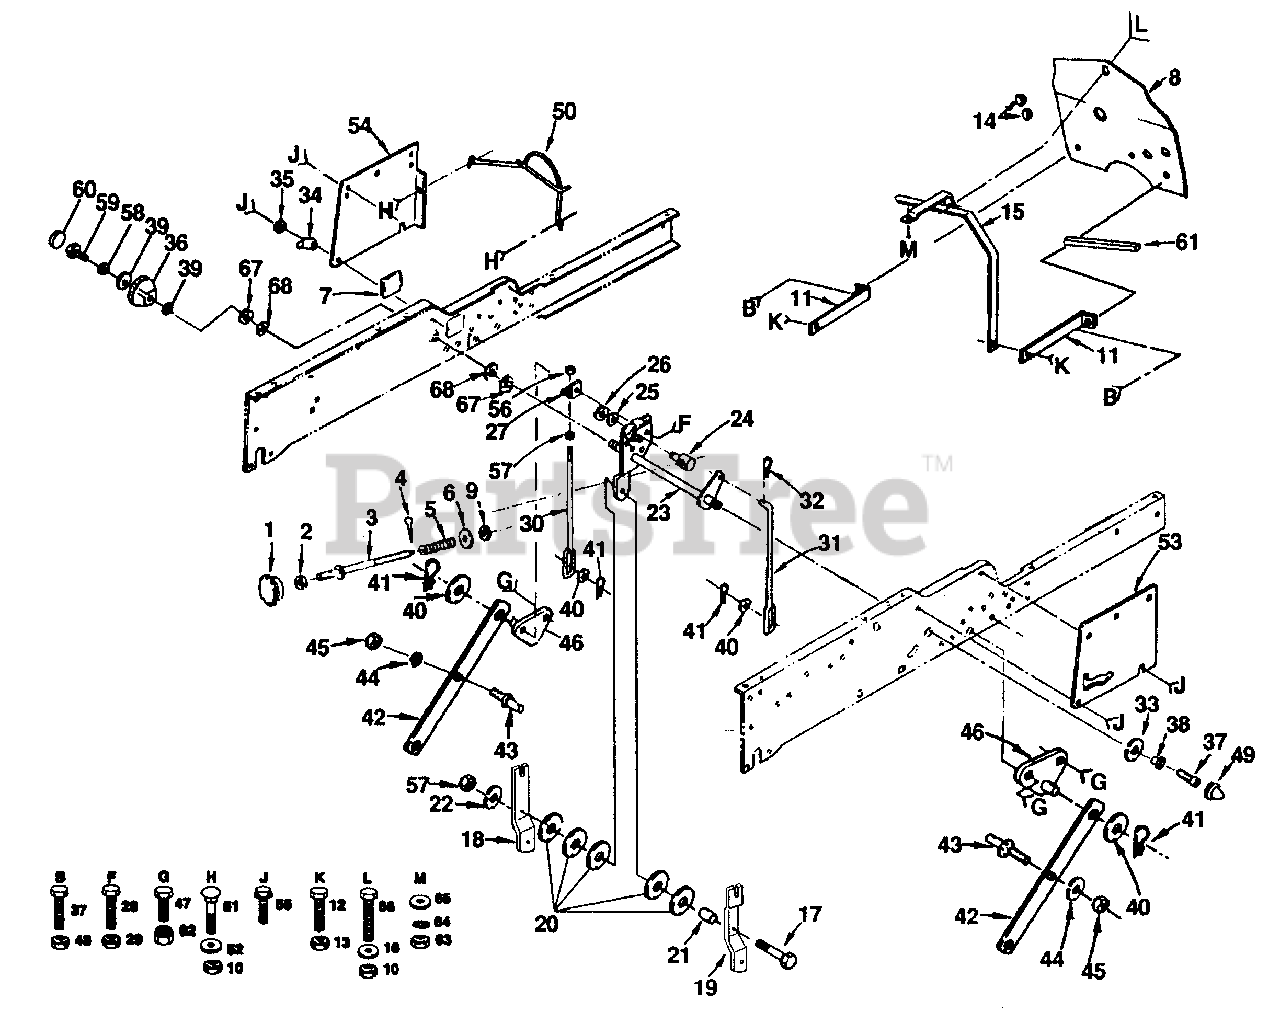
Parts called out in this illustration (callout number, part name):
1	Handle, Adjust, Lift
2	Nut, Hex, Jam 3/8-16
3	Rod, Adjust, Lift
4	Pin, Cotter 3/32 x 3/4
5	Spring
6	Washer 13/32 x 5/8 x 16 Gauge
7	Cover, Access
8	Shield, Head, Read
9	Nut, Special
10	Locknut 5/16-18
11	Brace, Head Shield
12	Bolt, Hex 1/4-20 x 1/2
13	Locknut 1/4-20
14	Grommet
15	Support Assembly, Dash
16	Washer 11/32 x 3/4 x 16 Gauge
17	Bolt 3/8-16 x 1-3/4
18	Bracket, Lift, L.H.
19	Bracket, Lift, R.H.
20	Washer 17/32 x 1-1/2 x 10 Gauge
22	Washer, Lock 3/8
23	Shaft, Lift
24	Trunnion, Stop Depth
25	Washer 15/32 x 3/4 x 16 Gauge
27	Bracket, Lift L.H.
28	Bolt, Shoulder
29	Nut, Hex Flange 1/4-20
30	Link, Lift, L.H.
31	Link, Lift, R.H.
32	Retainer, Spring
33	Washer, Lock Hvy. Hel. Spring
34	Pointer, Height Indicator
35	Washer, Nylon
36	Scale, Height Indicator
37	Bolt, Hex 3/8-16x1
38	Hub, Lift Shaft
39	Washer 11/32 x 1-1/2 x 10 Gauge
40	Washer 17/32 x 1 x 16 Gauge
41	Retainer, Spring
42	Arm, Suspension
43	Stud, Pivot, Center
44	Washer, Lock 1/2
45	Nut, Hex 1/2-13
46	Bracket, Suspension, Mower
47	Bolt, Carriage 3/8-16 x 3/4
48	Locknut 3/8-16
49	Cap, Spring
50	Guard, Belt, Engine
51	Bolt, Carriage 5/16-18 x 1
52	Washer 11/32 x 1 x 10 Gauge
53	Panel, Dash, R.H.
54	Panel, Dash, L.H.
55	Screw, Hex Wsh. Thdrol 3/8-16 x 1/2
56	Locknut 3/8-16
57	Nut, Hex 3/8-16
58	Washer, Lock H Helical Spring
59	Bolt, Hex Fin 5/16-18 x 1
60	Plug, Hole
61	Strip, Foam
62	Nut, Centerlock 3/8-16
63	Nut, Hex 1/4-20
64	Washer, Lock 1/4
65	Washer 9/32 x 3/4 x 16 Gauge
66	Bolt, Hex 5/16-18 x 3/4
68	Washer 29/32 x 1-1/4 x 16 Gauge
